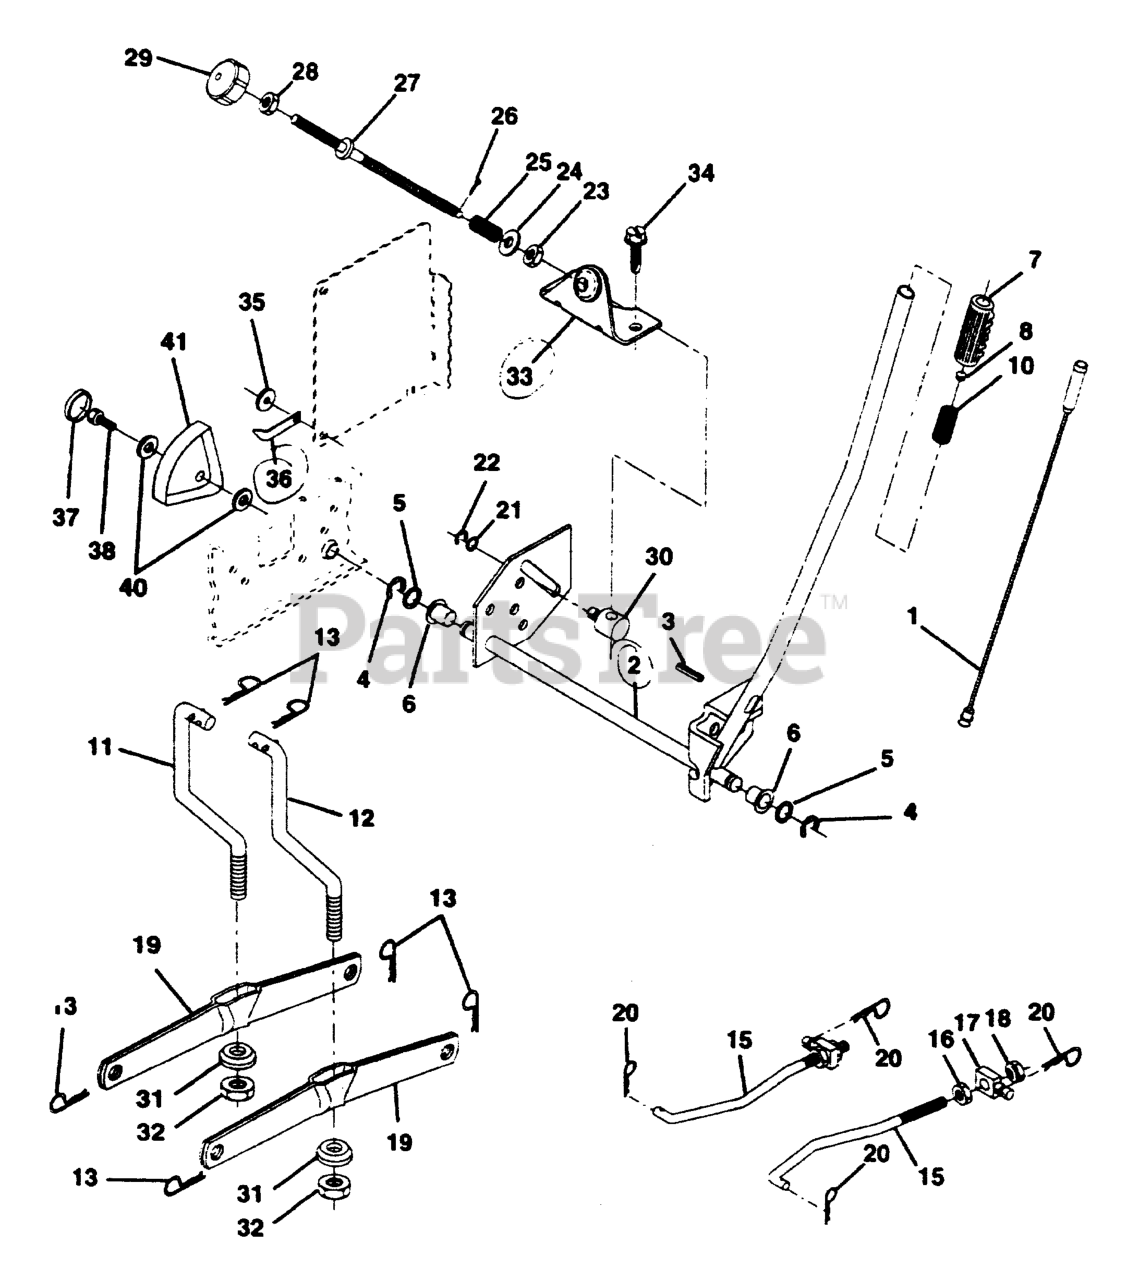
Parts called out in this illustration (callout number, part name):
1	WIRE.INNER.HANDLE.LIFT.LEVER
2	SHAFT ARM LIFT RH
3	PIN GROOVE.
4	RETAINING RING LT
6	BEARING.NYLON
7	GRIP HANDLE
8	PLUNGER BUT KIT
10	SPRING, COMP T
11	LINK LIFT LH
12	LINK LIFT RH
13	RETAINER-SPRNG RB
15	FRONT LINK
16	NUT.HEX.JAM.1/2-13
17	TRUNION
18	NUT.LK.W/WSH.1/2.
19	ARM.REAR.SUSPENSION
20	SPRING RETAINER
21	Washer 15/32 x 3/4 x 16 Gauge
22	Ring, Klip #T5304-37
25	SPRING**
26	COTTER PIN
27	ROD ADJ LIFT
28	NUT
29	KNOB INF 3/8-16
30	TRUNION LT
31	BEARING PIVOT
32	NUT CROWNLOCK 3/8-24
36	POINTER HGT
38	SCREW.THDROL.5/16-18X3/4.TTY
41	HEIGHT INDICATOR
